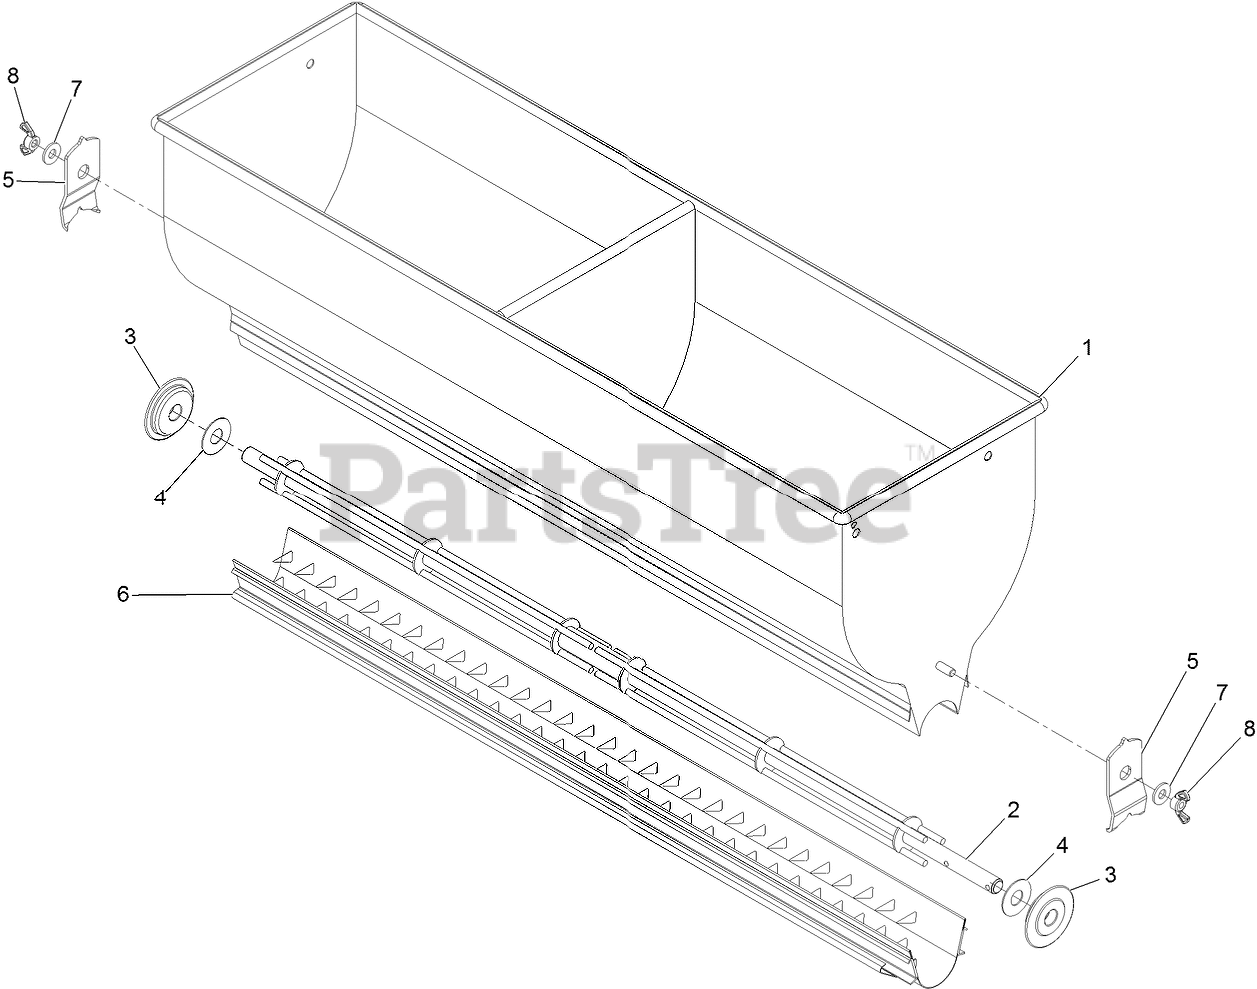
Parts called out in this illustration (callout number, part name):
1	Hopper-36 In. Seeder
2	Rotor-Bar 36 In. Seeder
3	Bearing-End Hopper
5	Retainer-End Bearing
6	SLIDE-METERING GATE
7	WASHER-FLAT
8	WINGNUT-NYLOCK
